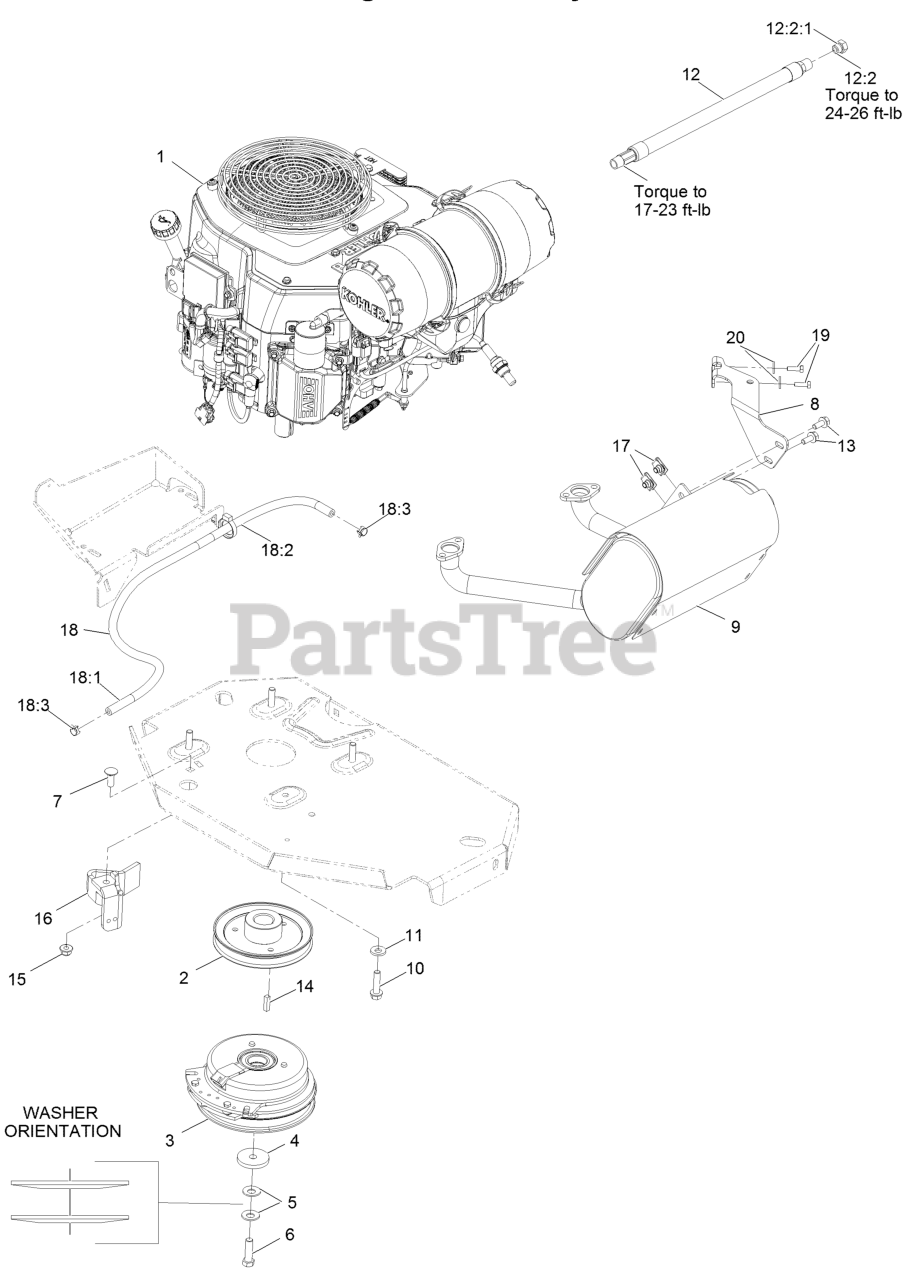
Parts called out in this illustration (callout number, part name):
2	SHEAVE
3	CLUTCH KIT
4	WASHER-CLUTCH
5	WASHER-SPRING
6	SCREW-HH 7/16-20 X 1 1/2 W/LOCTITE
7	SCREW-CARR
8	MUFFLER BRACKET KIT
10	SCREW-HWH
11	WASHER-BELLEVILLE
12	OIL DRAIN HOSE ASM
12:2	PLUG-HH
12:2:1	O-RING
13	SCREW-HHF
15	NUT-HF, NI
16	CLUTCH-ANCHOR
18	FUEL LINE ASM
18:1	HOSE-FUEL
18:2	SLEEVE-THERMAL
18:3	CLAMP-HOSE
19	SCREW-HH M6-1 X 20Mm W/Patch
20	WASHER-SPRING
